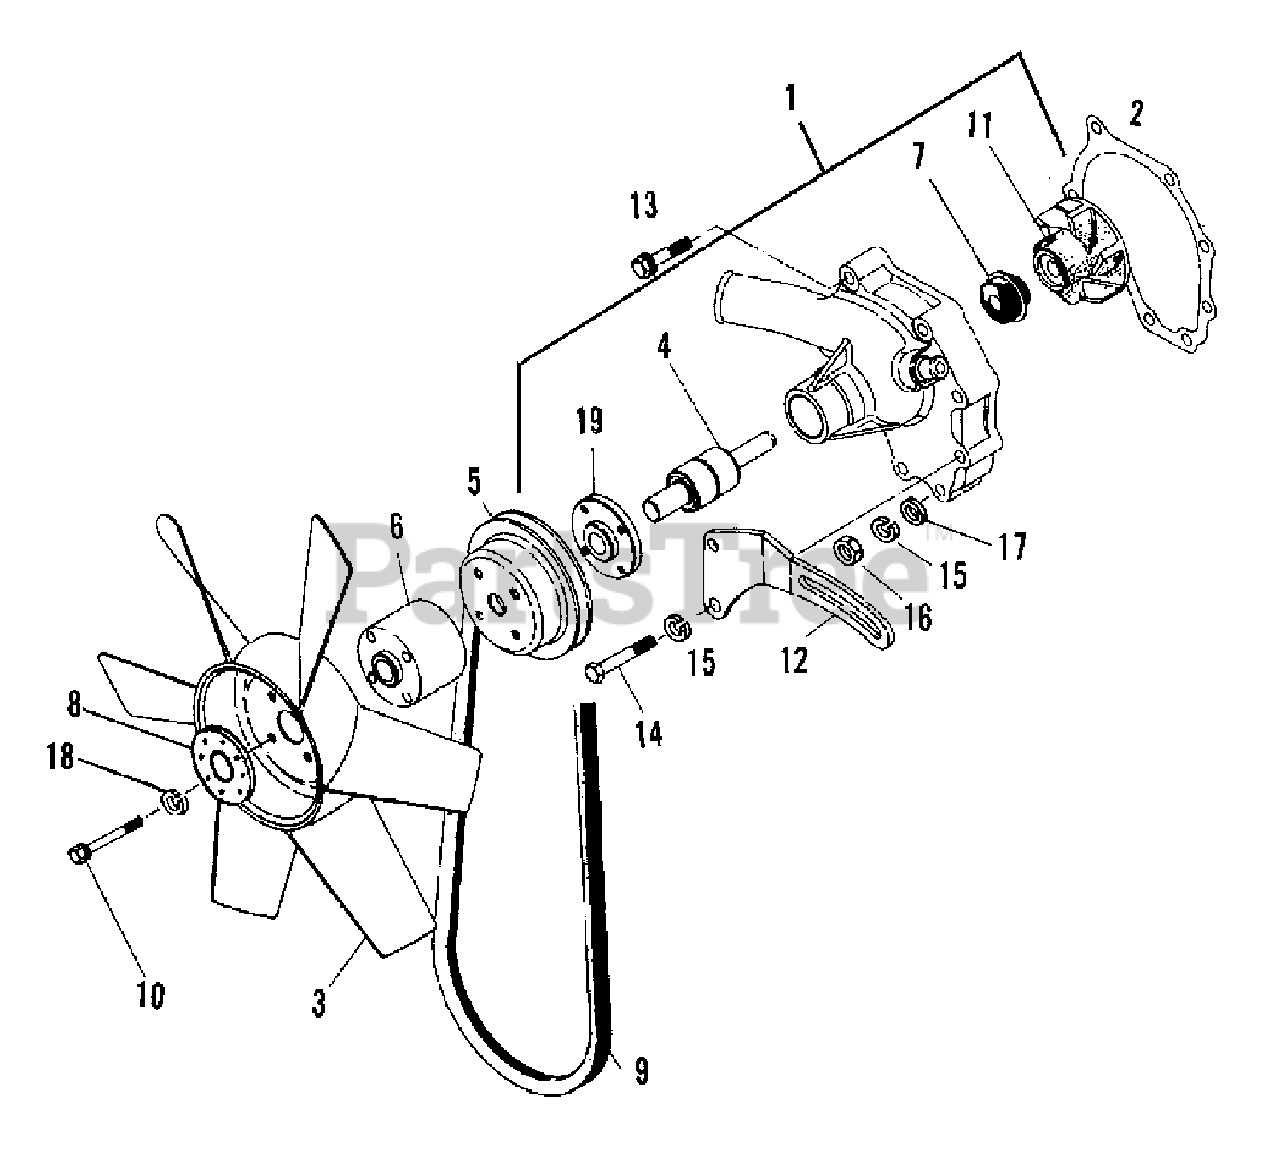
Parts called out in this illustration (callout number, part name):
1	PUMP ASSEMBLY KIT (Incl. Items 2, 4, 7, 11 & 19)
4	SHAFT ASSEMBLY (Not serviced; order 2097657 PUMP ASSEMBLY)
5	PULLEY, water pump
7	SEAL ASSEMBLY, (Not serviced; order 2097657 PUMP ASSEMBLY)
8	LOCKPLATE, fan bolts
9	BELT, fan
10	CAPSCREW, M6 x 63 fan
11	IMPELLER (Not serviced; order 2097657 PUMP ASSEMBLY)
12	SUPPORT, generator
13	CAPSCREW, M8 x 40 washer, lockwasher
14	CAPSCREW, M8 x 50
15	LOCKWASHER, M8
17	WASHER
18	LOCKWASHER, M6
